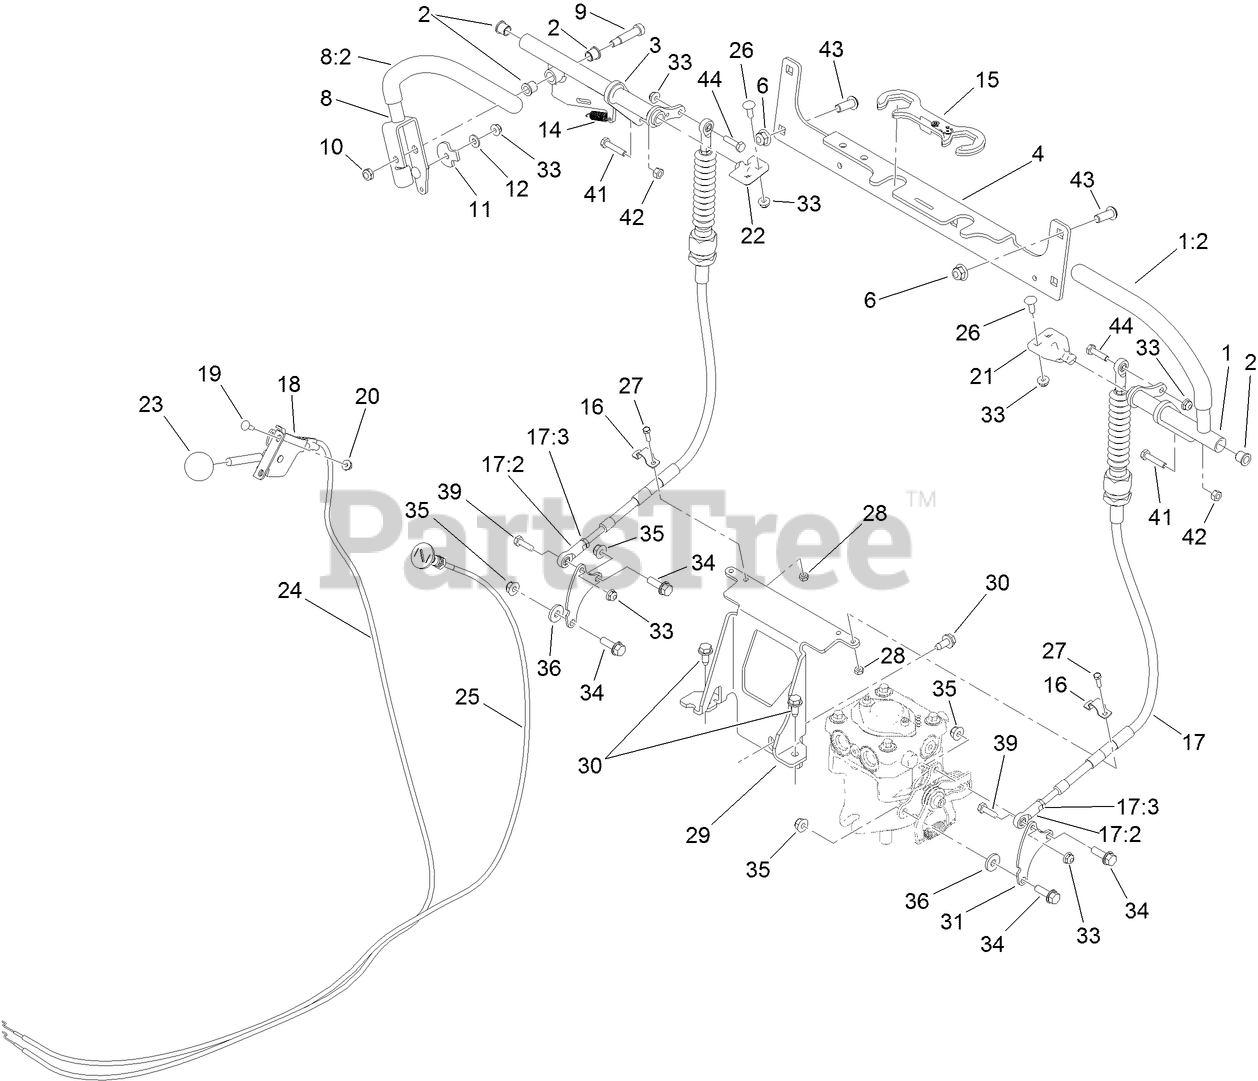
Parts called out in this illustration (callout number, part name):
1	LH LEVER ASM
2	BEARING
3	CONTROL-MOTION, RH
4	BRACKET-CROSS
6	NUT-HF, NI
8	LEVER-MOTION, RH
9	SCREW-HSH
10	NUT-LOCK, NI
11	CAM-LEVER
12	WASHER-FLAT
14	SPRING-EXTENSION
15	LOCK-CABLE
17	CABLE ASM
17:2	ROD END-BALL JOINT
17:3	NUT-JAM
18	LEVER-CONTROL
19	BOLT-CARR
20	NUT-LOCK, FLANGE
21	TAB-PIVOT, LH
22	TAB-PIVOT, RH
23	KNOB-BALL
24	CABLE-THROTTLE
25	CONTROL-CHOKE, PUSH/PULL
26	BOLT-CARR
28	NUT-LOCK, NI
29	BRACKET-MOUNT, CABLE
30	SCREW-HWHTF
31	PLATE-CONTROL, PUMP
33	NUT-HF
34	SCREW-HHF
35	NUT-HF, NI
36	WASHER-FLAT
39	SCREW-HH
41	SCREW-HH
42	NUT-HEX
43	SCREW-HSBH
44	SCREW-HH
